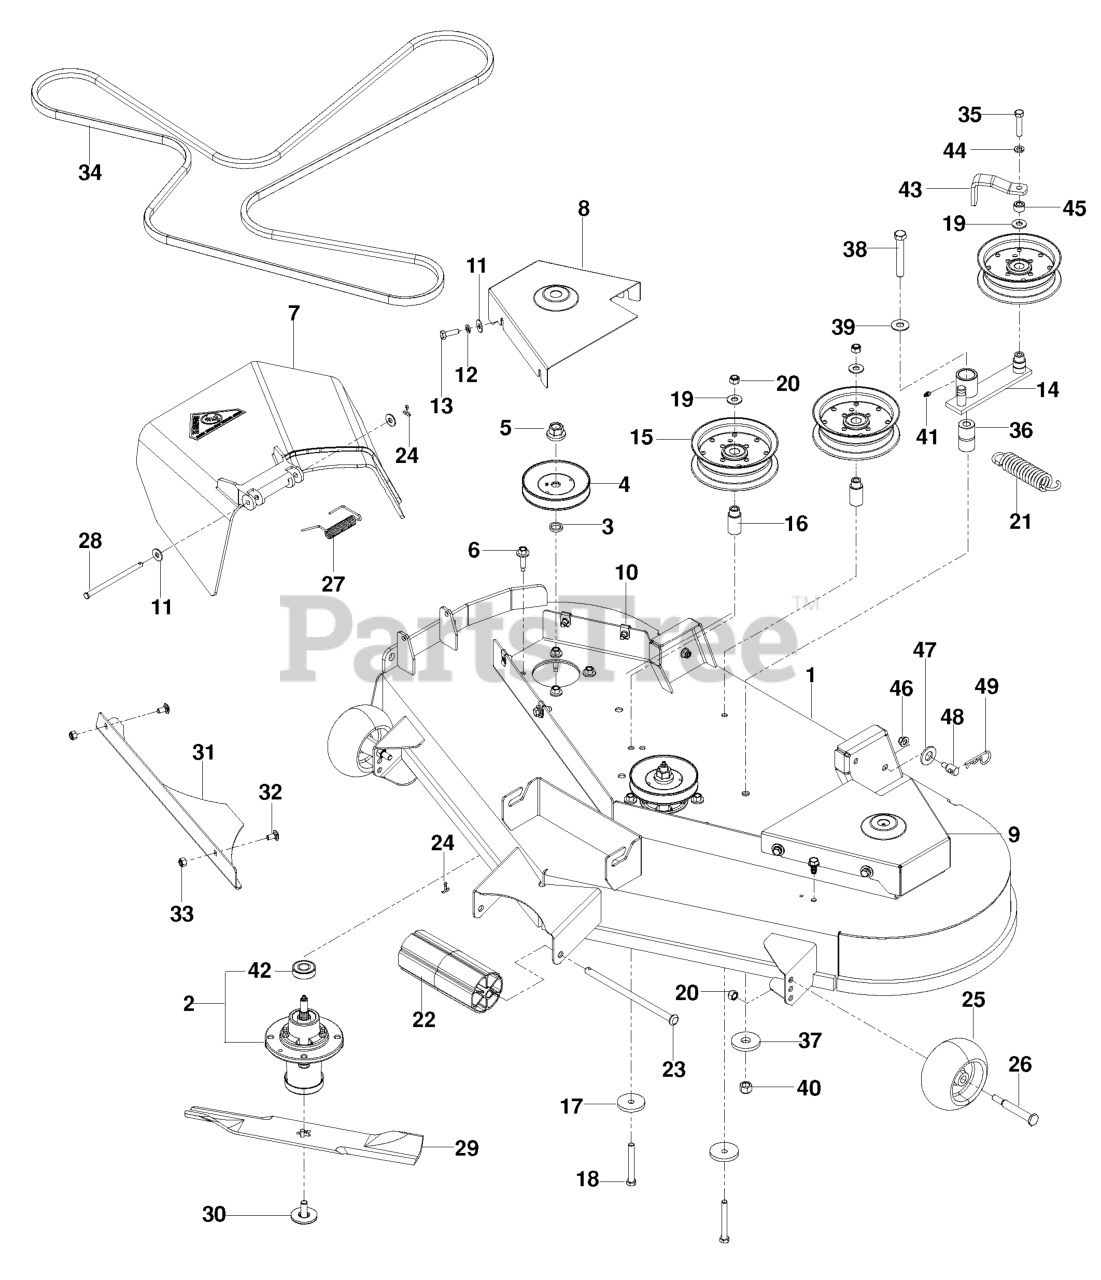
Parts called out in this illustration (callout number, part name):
1	DECK.48".TRI-FORCE.W/DECALS.OR
2	MANDREL.DECK.ASSEMBLY
3	WASHER-SPACER
4	MANDREL PULLEY
5	LOCKNUT - 9/16
6	WASHER HEAD SCREW
7	DISCHARGE CHUTE 48"
8	BELT SHIELD - R.H. ORANGE
9	BELT SHIELD - L.H. ORANGE
10	U-CLIP 5/16-18 NUT RETAINER
11	WASHER 5/16 FLAT
12	WASHER.LOCK.HVY.HLCL.SPR.5/16
13	HCS 5/16C X 3/4
15	PULLEY, IDLER
16	IDLER BUSHING
17	SPINDLE WASHER
18	HCS 3/8C X 3
19	WASHER 3/8 FLAT
20	NUT 3/8-16 NYLOC
22	NOSE ROLLER 48"
23	ROD.ROLLER.NOSE.NARROW.48"
24	RP_COTTER PIN 1/8 X 3/4
25	GAUGE WHEEL
26	SHOULDER BOLT 1/2X2-5/8 ZD SPE
27	SPRING - TORSION
28	PIN-CLEVIS 5/16 DIA X 5.19 ZD
29	BLADE, 16-1/4"
30	BLADE BOLT ASSY-7/16" TB REPL
31	CONFINEMENT PLATE 48" BLK
32	CARRIAGE BOLT 5/16C X 5/8"
33	NUT 5/16 NYLOC
34	BELT, DECK
35	HCS 3/8-16 X 1 3/4 GR5
36	PIVOT BUSHING
37	WASHER, SUPPORT
38	HCS 1/2C X 3 1/4
39	WASHER 1/2 FLAT
40	NUT 1/2-13 HEX NYLOC ZD
41	ZERK
42	BEARING, BALL
43	GUIDE, BELT
44	FLAT WASHER 5/16 SAE
46	5/16-18 NYLOC FLANGE NUT
47	WASHER 5/8 FLAT
48	STUD.FASTNER.W/ANTI-ROTATE
49	HAIRPIN #4
